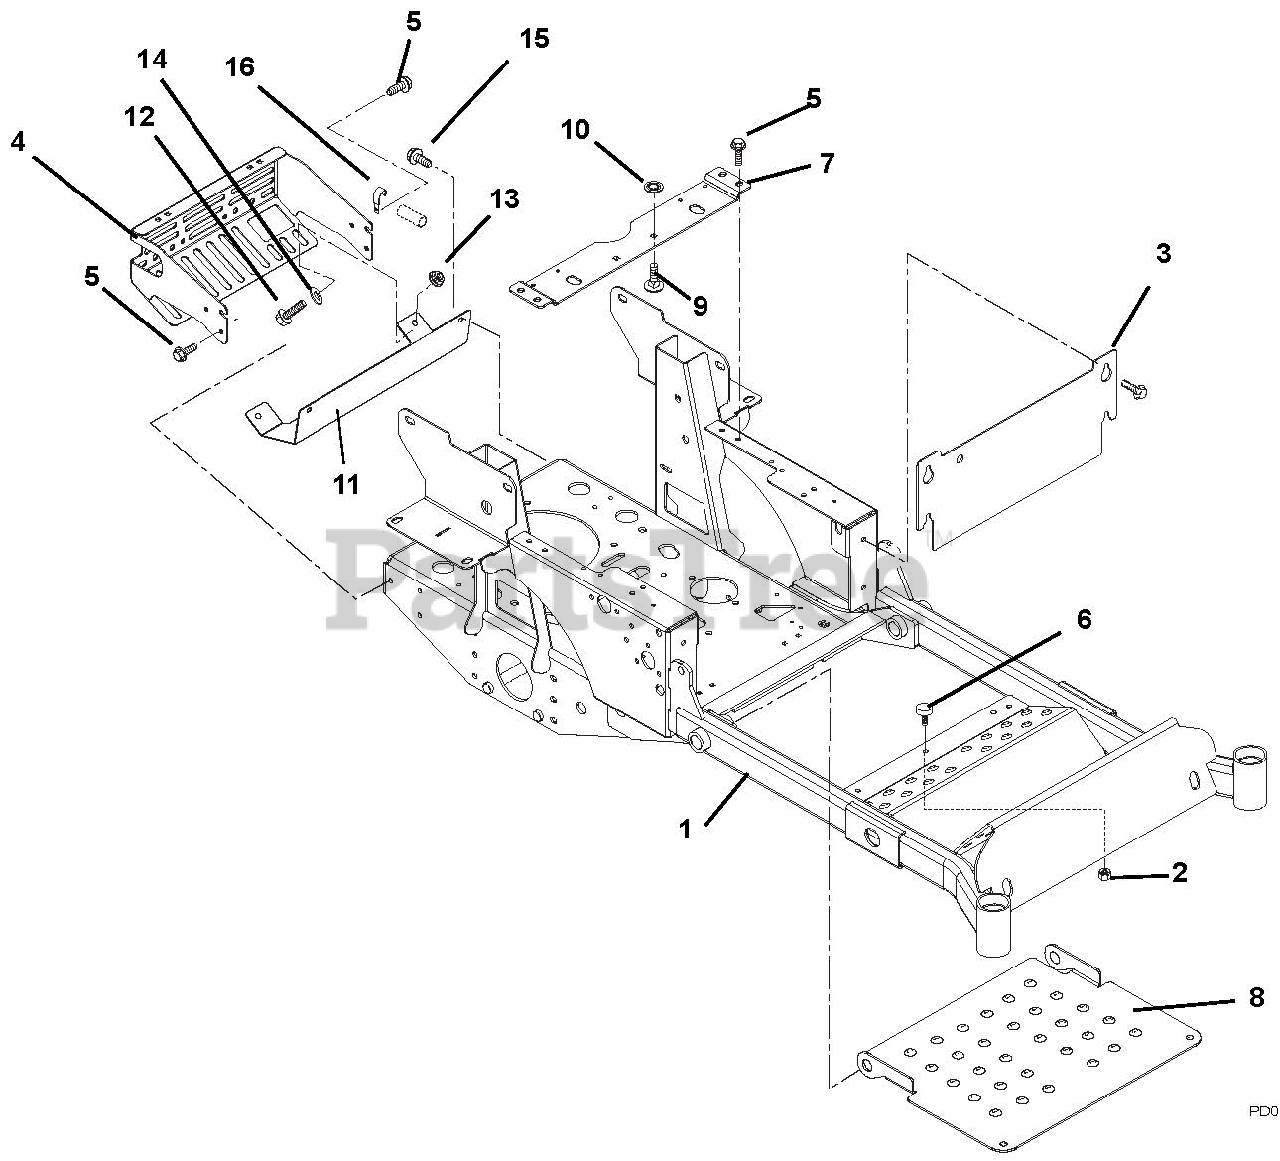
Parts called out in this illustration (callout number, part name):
1	Frame, Compact-Z
2	Nut, Spin Lock Flange .312-18
3	Access Panel
4	Bumper, Rear
5	Screw, Tapping .38-16 x .75 Hex Washer Head
6	Bumper, Rubber
7	Seat Support
8	Panel, Inspection
9	Bolt, Round Head Square Short Neck .31-18 x .74 Grade 5
10	Nut, Push .312
11	Heat Shield, Compact Z
12	Bolt, Hex .38-16 x .75 Grade 5
13	Nut, Nyloc Flange .38-16
14	Washer, Flat Steel .438 x 1.00 x .083
15	Screw, Tapping .38-16 x .50 Hex Washer Head
